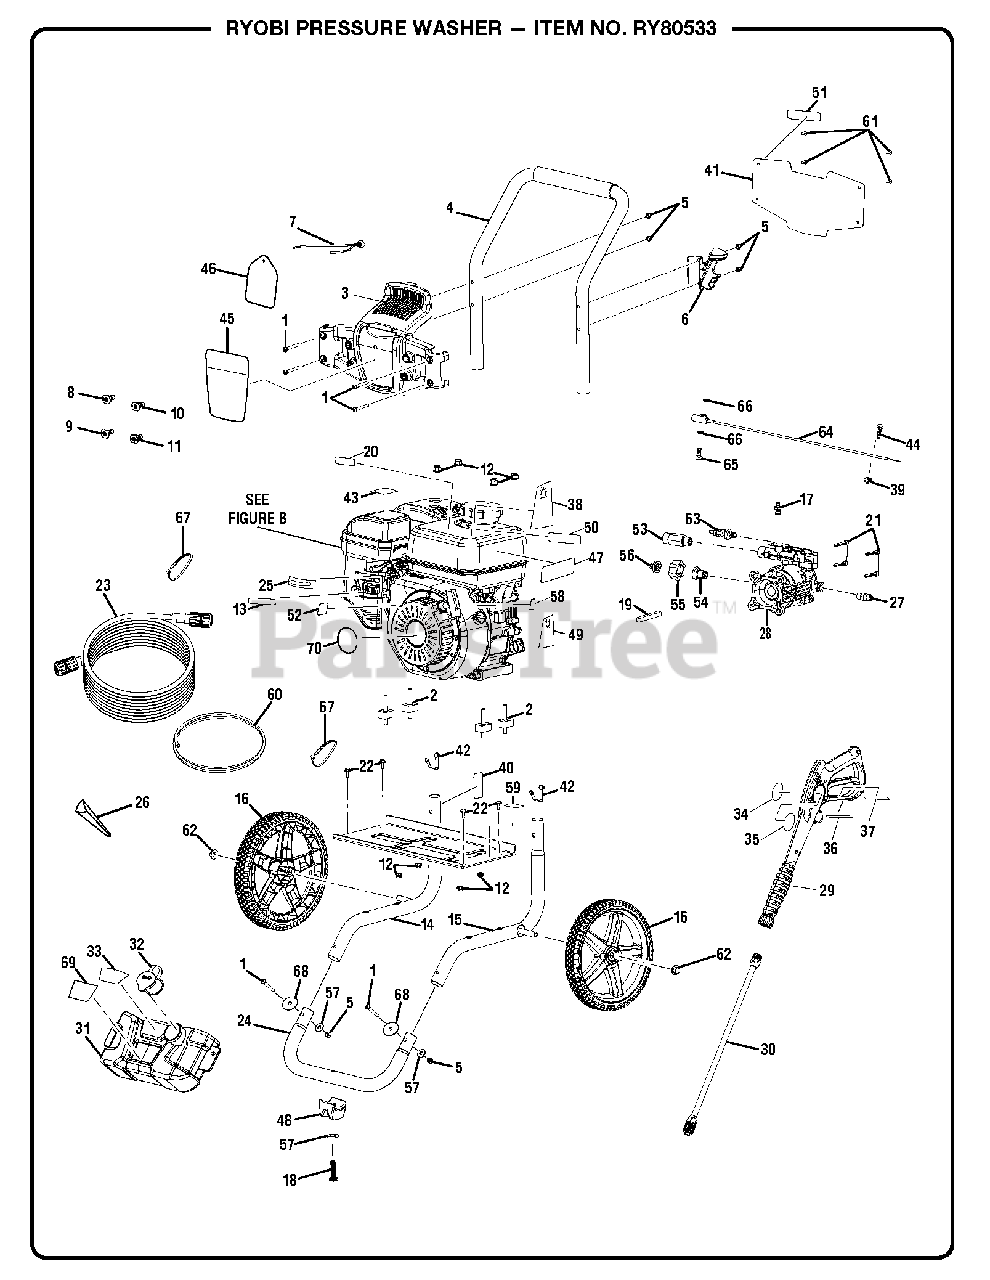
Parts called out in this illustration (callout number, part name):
1	Screw (M6 x 48 mm, T30 Torx Hd.)
2	Engine Isolator
3	Hose and Nozzle Holder Assembly
4	Handle w/Foam
5	Lock Nut (M6)
6	Wand Holder
7	Bungee Cord Assembly
8	40 deg Nozzle
9	Soap Nozzle
10	25 deg Nozzle
11	0 deg Nozzle
12	Flange Nut (M8 x 1.25)
13	Fuel On-Off Label
14	Main Frame Assembly
15	Main Frame Assembly
16	Wheel
17	Detergent Suction Kit
18	Bolt (M6 x 25 mm, T30 Torx Hd.)
19	Output Shaft Key (40 mm)
20	Do Not Mix Label
21	Bolt (5/16-24 x 23 mm, Soc.Hex Hd.)
22	Flange Bolt (M6 x 16 mm)
23	Hose (25 ft.)
24	Front Frame
25	Choke Label
27	Thermal Release Valve
29	Trigger Handle Assembly
30	Extension Wand
31	Soap Tank
32	Soap Tank Cap
33	Soap Dilution Label
34	Label (Wand Logo)
35	Warning Label (En)
36	Warning Label (Fr/Sp)
37	Label (Wand Rating)
38	Danger Hangtag
39	Cable Clamp
40	Combustion Warning Label
41	Quick Start Panel
42	Lock Button w/Spring Clip
43	Hot Surface Label
44	Bolt (M5 x 20 mm)
45	Performance Label
46	Nozzle Hangtag
47	Danger Label
48	Rubber Foot
49	Dipstick Hangtag
50	No E85 Label
51	Inquiries Label
52	Fuel Valve Label
53	Outlet Tube
56	Filter Screen (Pump Inlet)
57	Washer (1/4 in.)
58	Engine On/Off Label
59	Oil Fill Location Label
60	Chemical Siphon Tube
61	Screw (#6-20)
62	Push Cap Nut
63	Unloader Valve Assembly
64	Idle Down Throttle Valve Assembly
65	Bolt (M10 x 1-1/2, Banjo)
66	Bonded Compression Seal
68	Fender Washer (1/4 in.)
69	Soap Tank Label
70	Recoil Label
